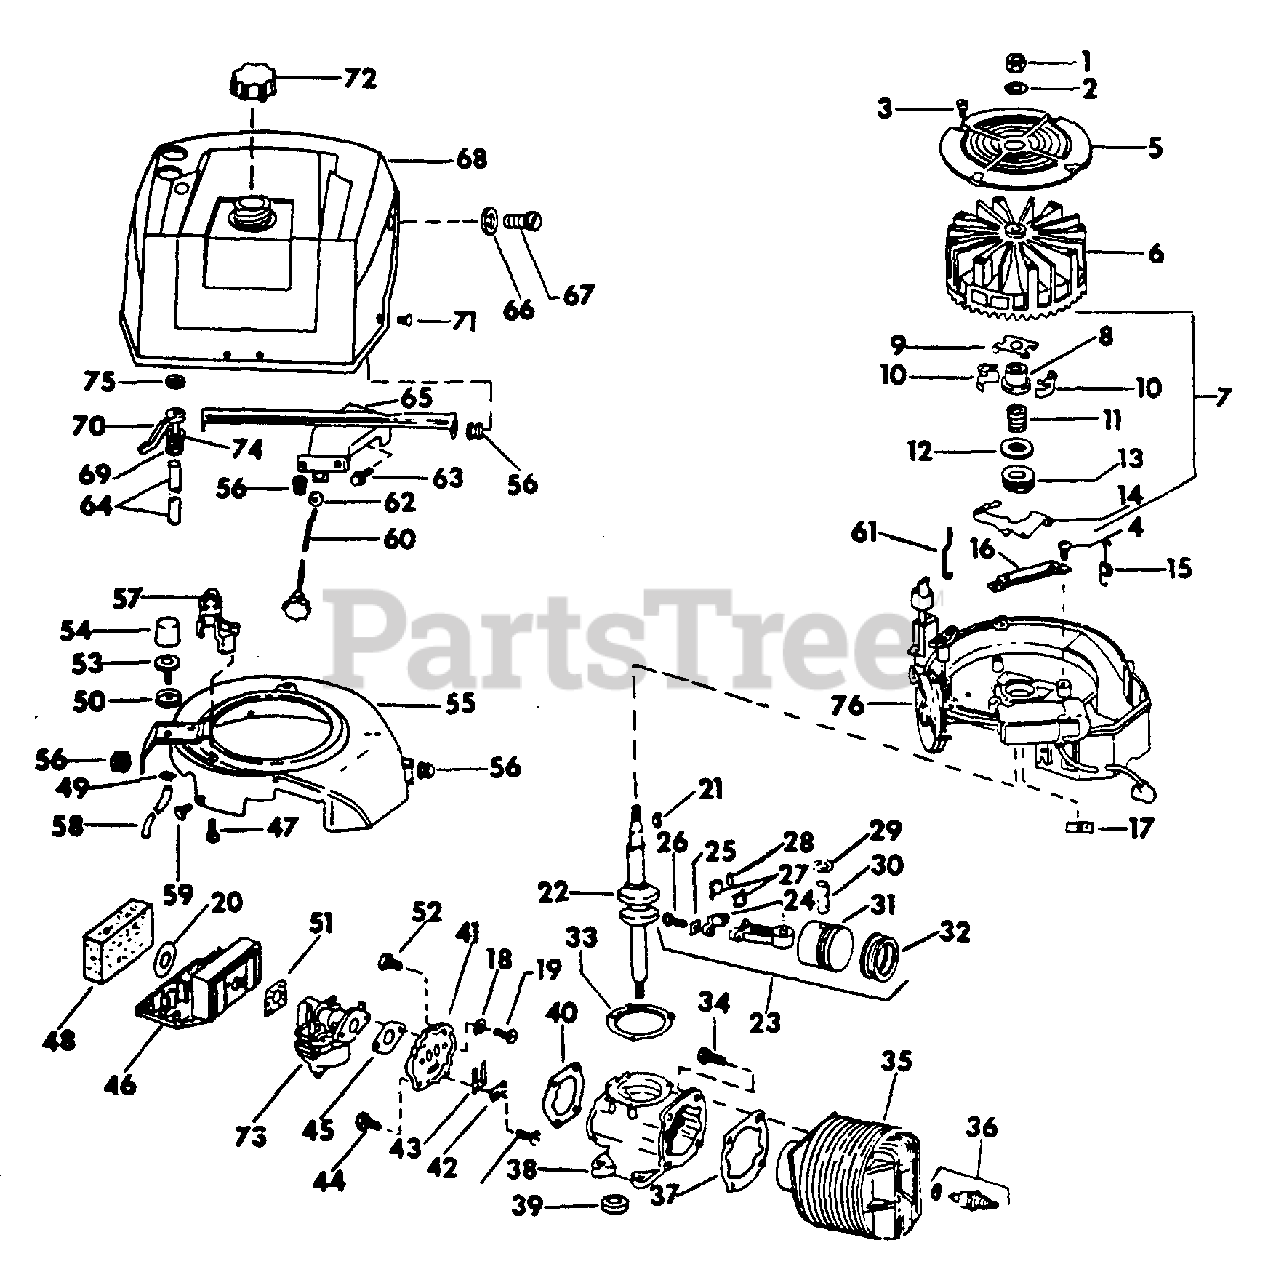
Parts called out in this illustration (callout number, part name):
1	NUT, 7/16-20 HEX.
2	WASHER, 7/16 ZND INT TOOTH LOCK
3	SCREW, 10-24 X 1/2 TRUSS-HD REC TAP.
4	SCREW, 5/16-18 X 1-3/8 ZND HEX-HD CAP
5	SCREEN, FLYWHEEL
7	GOVERNOR ASSY
8	COLLAR, GOVERNOR
9	YOKE, GOVERNOR
10	WEIGHT, GOVERNOR
11	SPRING, GOVERNOR
12	WASHER, THRUST
13	COLLAR, THRUST
14	LEVER, GOVERNOR
15	SPRING, VARIABLE SPEED
16	BRACKET, GOVERNOR LEVER
21	KEY, CRANKSHAFT
23	PISTON & CONNECTING ROD ASSY
24	ROD ASSY, CONNECTING
25	LOCKPLATE, SCREW
26	SCREW, CONNECTING ROD
27	LINER, CONNECTING ROD
28	BEARING SET, NEEDLE
29	RING, RETAINING
32	RING SET, PISTON - 2 RINGS
33	GASKET, CRANKCASE TO ARM PLATE .010
34	SCREW, CYL TO CRANKCASE
36	SPARK PLUG & GASKET
37	GASKET, CYL TO CRANKCASE
38	CRANKCASE & SEAL ASSY
40	GASKET, REED PLATE
41	REED PLATE ASSY
42	PLATE, BACKUP
44	SCREW, HH REED PLATE TO CRANKCASE
45	GASKET, CARBURETOR
46	FILTER ASSY, AIR
48	ELEMENT, FILTER
52	SCREW, HH REED PLATE TO CRANKCASE
54	BULB, PRIMER
55	BAFFLE ASSY, AIR
57	BRACKET & EYELET
61	ROD, GOVERNOR
65	BRACKET, SHROUD
68	SHROUD, TANK & VALVE ASSY
69	CLIP, SPRING
71	SCREW, COVER MTG
73	CARBURETOR ASSY
76	MAGNETO ASSY
